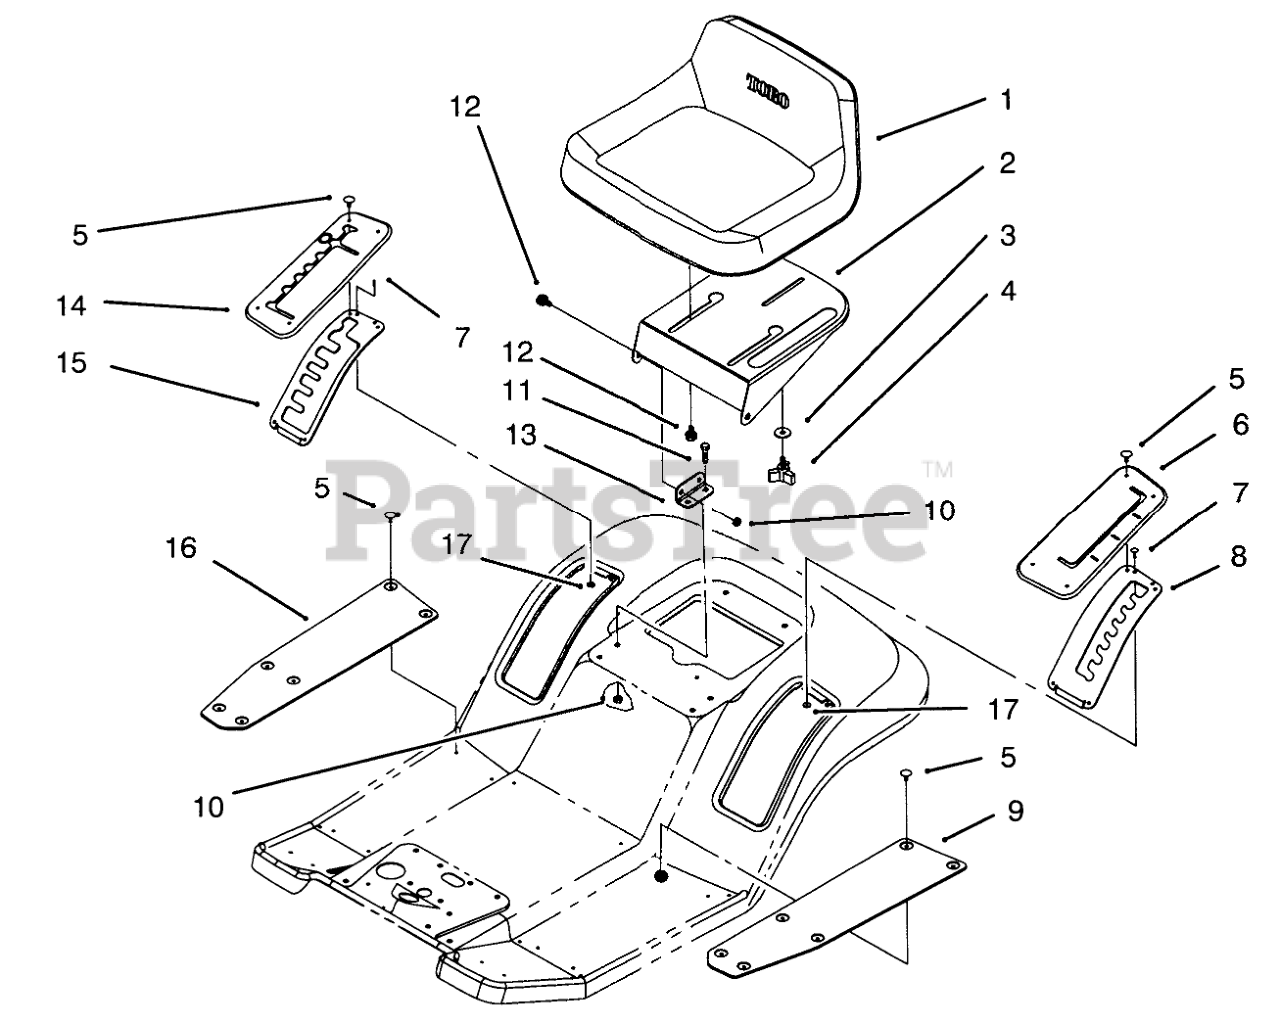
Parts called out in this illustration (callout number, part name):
1	SEAT
2	Support-Seat
3	WASHER-PIVOT
5	FASTENER-PANEL
6	COVER-HOC
7	RIVET-BLIND
8	Gate-H.O.C.
9	MAT-FOOT, LH
10	NUT-LOCK, NI
11	SCREW-HH
12	BOLT-SHOULDER
13	Bracket-Seat Hinge
14	COVER-GATE, SHIFT
15	Gate-Shift
16	MAT-FOOT, RH
17	WASHER-PLAIN
